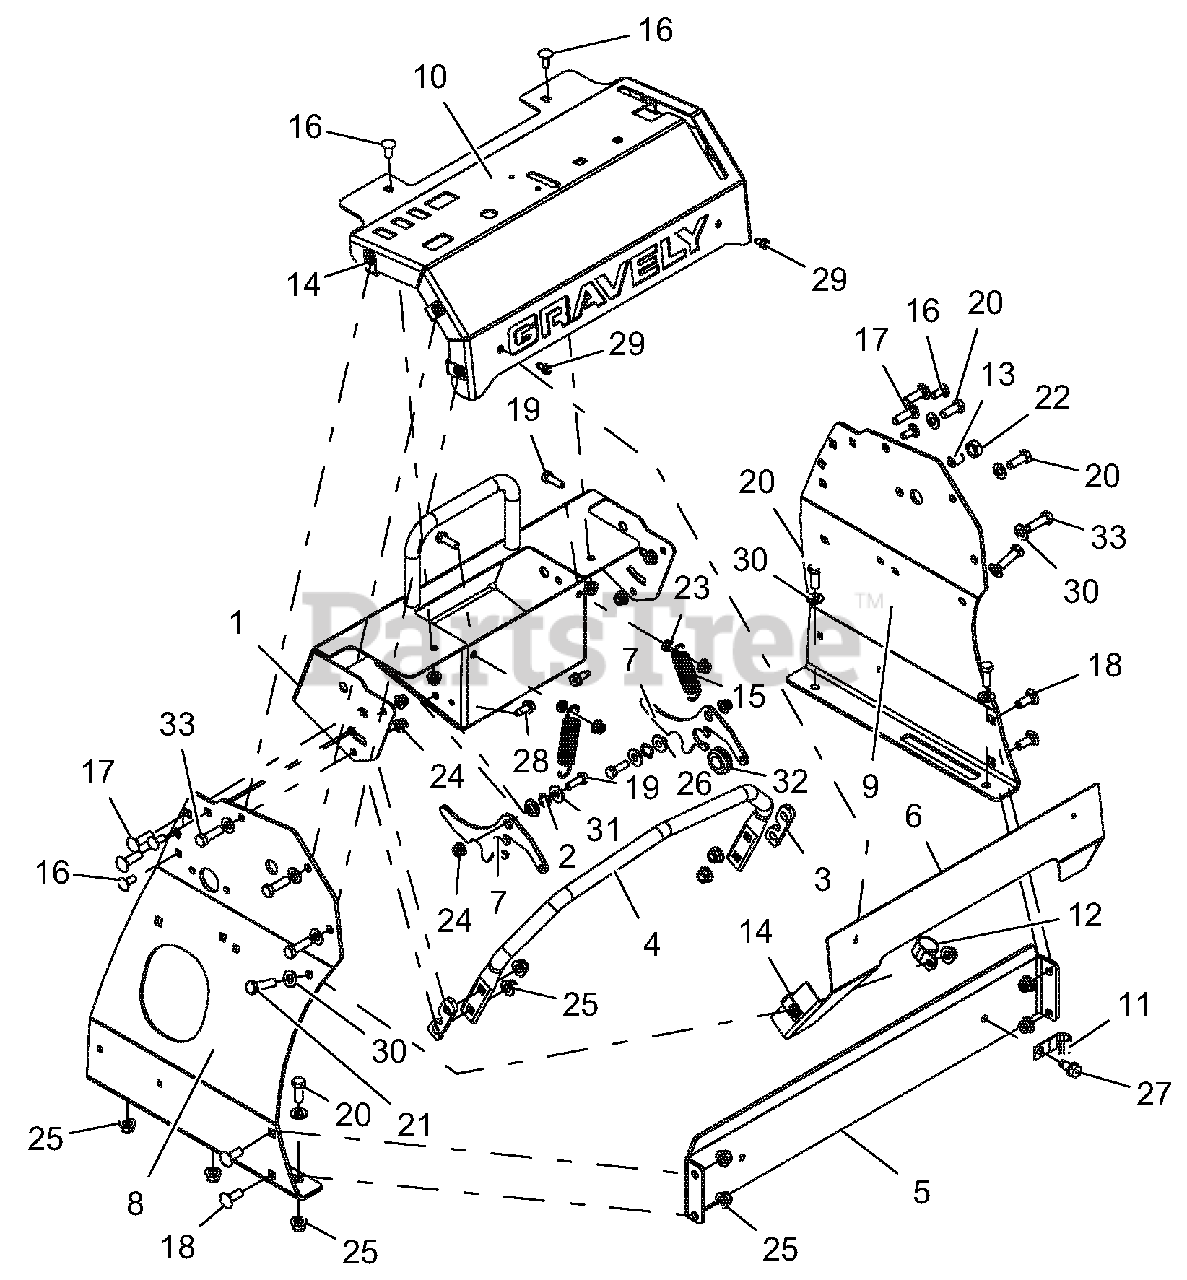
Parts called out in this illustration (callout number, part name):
1	WLDMT, CONTROL PANEL, PRO-STANCE
2	WAVE WASHER .531X.781X.125 FH
3	SHIM, BAR 5 DEG SPEED-BLACK
4	STOP, FORWARD STEERING
5	STIFFENER, TOWER
6	PLATE, FRONT BACKER
7	LATCH, PAD MOUNT
8	PANEL, TOWER RH, PRO-STANCE
9	PANEL, PROSTANCE LH TOWER
10	KIT, DASH WITH DECAL EFI
12	CLAMP, CUSHIONED STEEL REV
13	BALL SPRING PLUNGER, .500-13
14	NUT, RTNR .375-16X.37
15	SPRG, EXTENSION
16	BLT-RDHDSQNK .31-18X.75 G5 YWZC
17	BLT-RDHDSQNK .38-16X1.25 G5 YWZC
18	BLT-RDHDSQNK .38-16X1.00 G5 YWZC
19	BLT-HEX .31-18X1.00 GR5 YWZC
20	BLT-HEX .38-16X1.00 GR5 YWZC
21	BLT-HEX .38-16X1.50 GR5 YWZC
22	NUT, JAM .500-13 YWZC
23	@NUT-LK-CTR-JAM .31-18 YWZC
24	NUT-LK-NYL-FLG .31-18 YWZC
25	NUT-LK-NYL-FLG .38-16 YWZC
26	BSHG, FLG .32X.500.344X.880
27	SCR-TAP .38-16X.75 HWH TR YWZ
28	SCR-TAP .31-18X.75 HWH TR YWZ
29	SCR-TAP .25-20X.50 HWH TR YWZ
30	WSHR-FL-STL.406X.812X.065 YWZ
31	WSHR-FL-STL.38X.875X.083 YWZC
32	GROMMET, SPLIT RUBBER
33	BLT-HEX .38-16X1.25 GR5 YWZC
